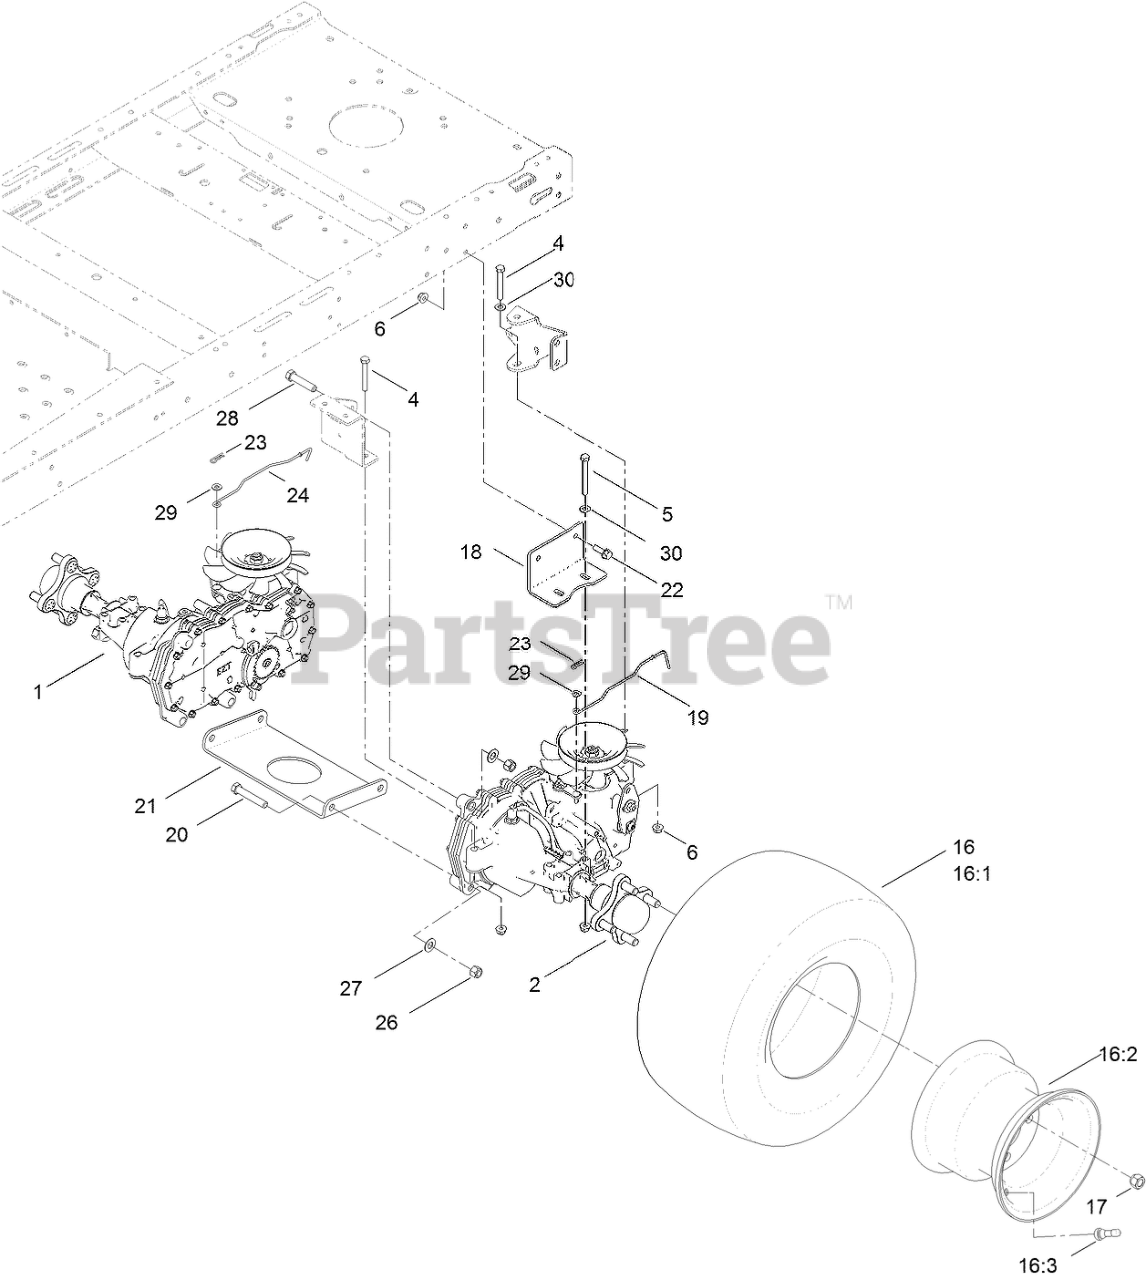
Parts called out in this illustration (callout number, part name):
1	RH HYDRO TRANSAXLE ASM
2	LH HYDRO TRANSAXLE ASM
4	SCREW-HH
5	SCREW-HH
6	NUT-HF, NI
16	4 PLY WHEEL AND TIRE ASM
16:1	TIRE-4 PLY
16:3	STEM-VALVE
17	NUT-LUG
18	MOUNT-HYDRO
19	ROD-BYPASS, LH
20	SCREW-HH
21	PLATE-CROSS, HYDRO
22	SCREW-HHF
23	PIN-COTTER
24	ROD-BYPASS, RH
26	NUT-LOCK, NI
27	WASHER-FLAT
28	SCREW-HH
29	WASHER
30	WASHER-PLAIN
